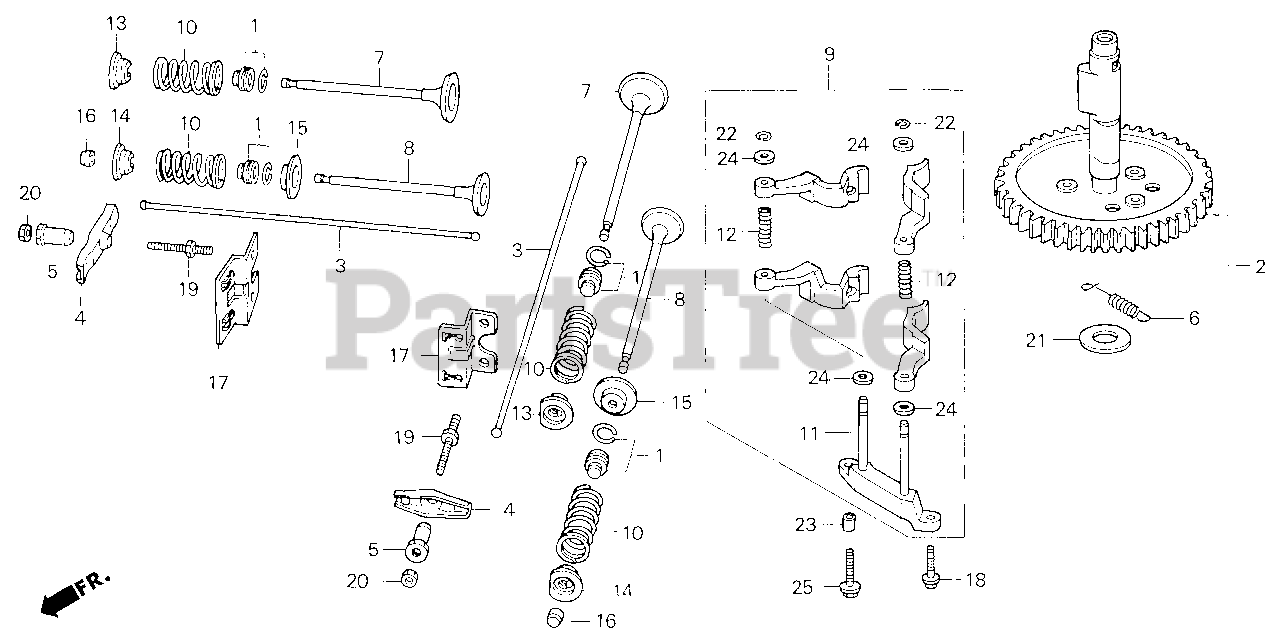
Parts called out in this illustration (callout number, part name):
1	SEAL, VALVE STEM
2	CAMSHAFT ASSY.
3	ROD, PUSH
4	ARM, VALVE ROCKER
5	PIVOT, ROCKER ARM
6	SPRING, WEIGHT RETURN
7	VALVE, IN.
8	VALVE, EX.
9	LIFTER ASSY., VALVE
10	SPRING, VALVE
11	SHAFT, VALVE LIFTER
12	SPRING, VALVE LIFTER
13	RETAINER, IN. VALVE SPRING
14	RETAINER, EX. VALVE SPRING
15	SEAT, VALVE SPRING
16	ROTATOR, VALVE
17	GUIDE, PUSH ROD
18	BOLT, FLANGE (5X16)
19	BOLT, PIVOT (8MM)
20	NUT, PIVOT ADJ.
21	WASHER, THRUST (17.2MM)
22	CLIP, GOVERNOR HOLDER
23	PIN A, DOWEL (8X12)
24	WASHER, PLAIN (6MM)
25	BOLT, FLANGE (6X25)
